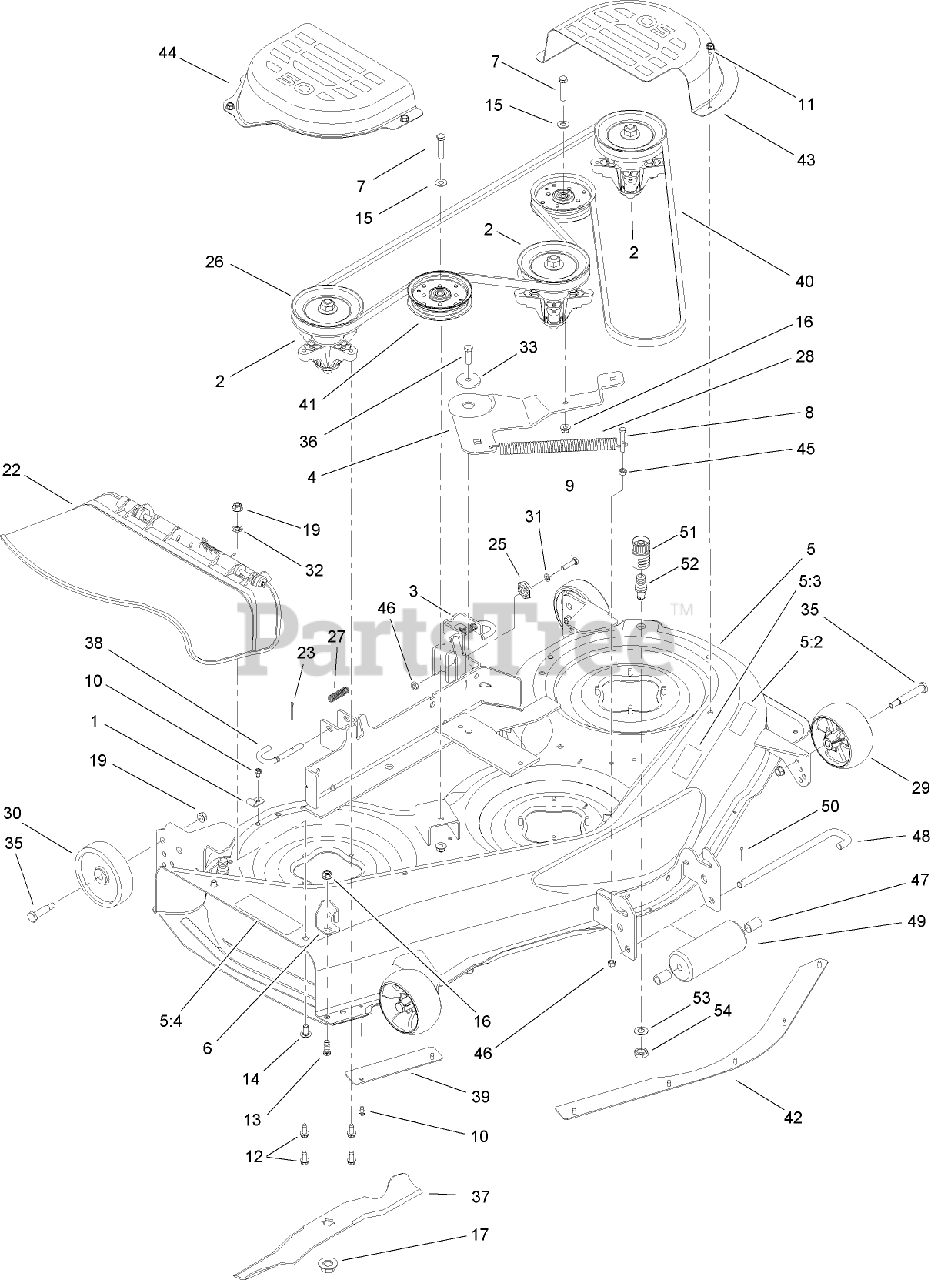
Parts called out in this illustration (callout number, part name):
1	BRACKET-RETAIN, HOOK
3	LH HANGER BRACKET ASM
4	WASHER-BELL
5	DECK AND DECAL ASM
5:3	DECAL-BELT ROUTING, DECK
5:4	DECAL-DANGER
6	STOP-CHUTE
7	SCREW-HH
8	SCREW-HH
9	SCREW-HH
10	SCREW-HWHTF
11	SCREW-HH, TAP
12	SCREW-HWH
13	SCREW-HH
14	BOLT-CARR
15	WASHER-FLAT
16	NUT-LOCK, FLANGE
17	NUT-LOCK, FLANGE
19	NUT-LOCK, FLANGE
22	CHUTE ASM
23	PIN-COTTER
25	GEAR-ADJUSTMENT, DECK
26	PULLEY-DECK
27	SPRING-COMPRESSION
28	SPRING-EXTENSION
29	WHEEL-DECK, FRONT
30	WHEEL-DECK, REAR
31	WASHER-LOCK
32	RETAINER-BOLT
33	SPACER-SHOULDER
35	BOLT-SHOULDER
36	SCREW-HH
37	BLADE-17.90 INCH
38	PIN-HANDLE, DECK RELEASE
39	SKIRT-RH
40	BELT-V, TYPE B
41	PULLEY-IDLER
42	SKIRT-CENTER
43	COVER-BELT, LH
44	COVER-BELT, RH
45	NUT-HEX
46	NUT-LOCK, FLANGE
47	SPACER
50	PIN-COTTER
51	ADAPTER-NOZZLE, WATER
52	NOZZLE-WATER, DECK
53	WASHER-LOCK
54	NUT-HEX
